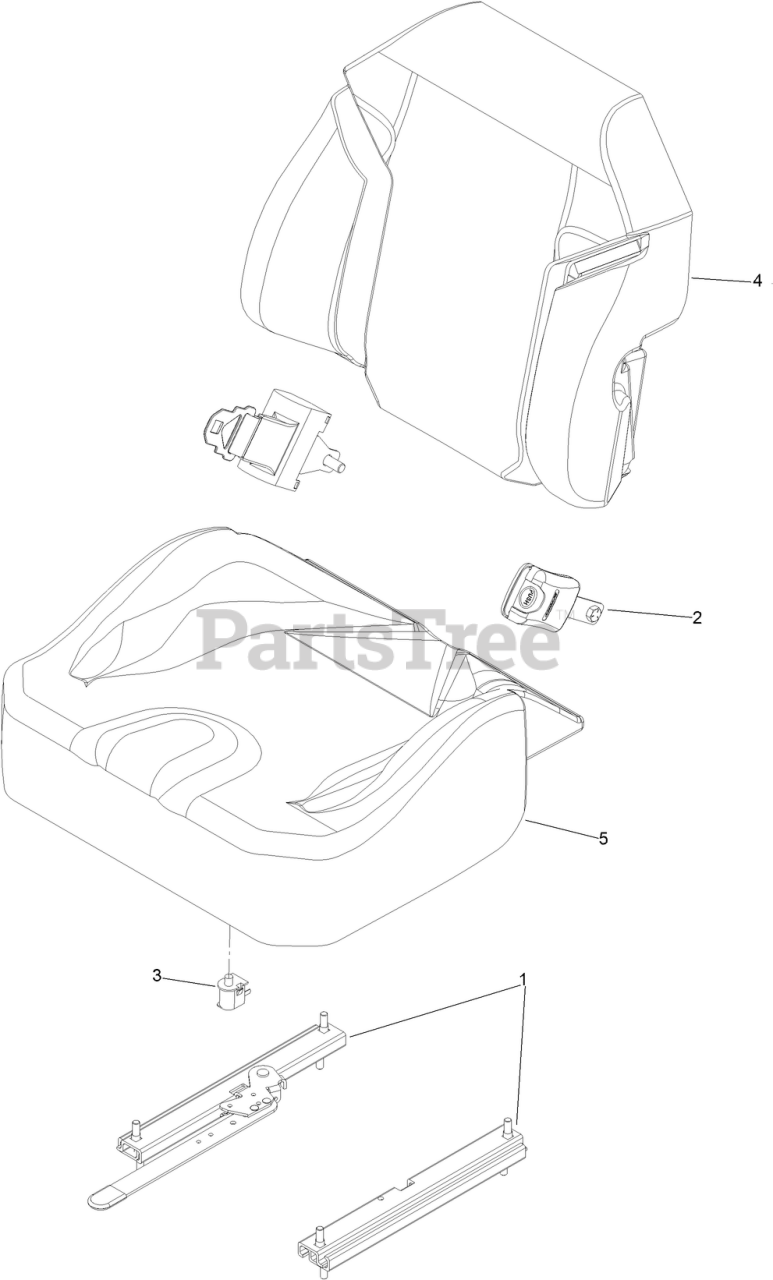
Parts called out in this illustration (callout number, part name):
1	SEAT TRACK KIT
2	SEAT BELT KIT
3	SWITCH-BAIL
4	COVER-BACK, SEAT
5	COVER-BOTTOM, SEAT
